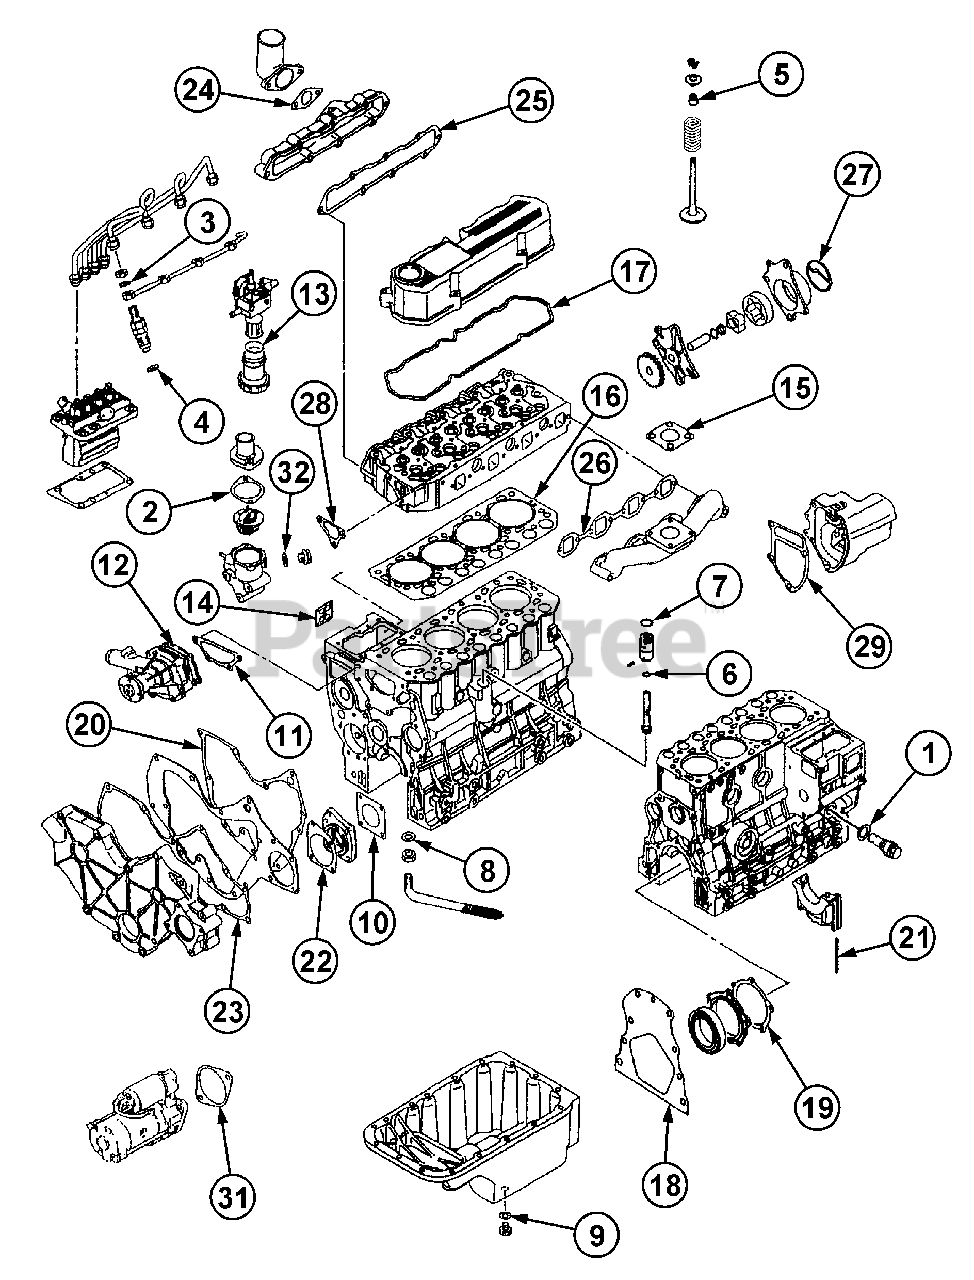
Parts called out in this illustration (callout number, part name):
2	Gasket
4	Gasket, Holder
5	Seal, Valve Stem
7	O-Ring
10	Gasket, Oil Pump
11	Gasket, Water
12	Gasket, Water
13	O-Ring, Filter
15	Gasket, Muffler
16	Gasket, Cyl/Head
17	Gasket, Rocker
20	Gasket
22	Gasket, Housing
23	Gasket, Gearcase
24	Gasket, Inlet
25	Gasket, Inlet
26	Gasket, Exhaust
27	Packing, Body
28	Gasket, Thrmo
29	Gasket, Gov Case
31	Gasket, Starter
